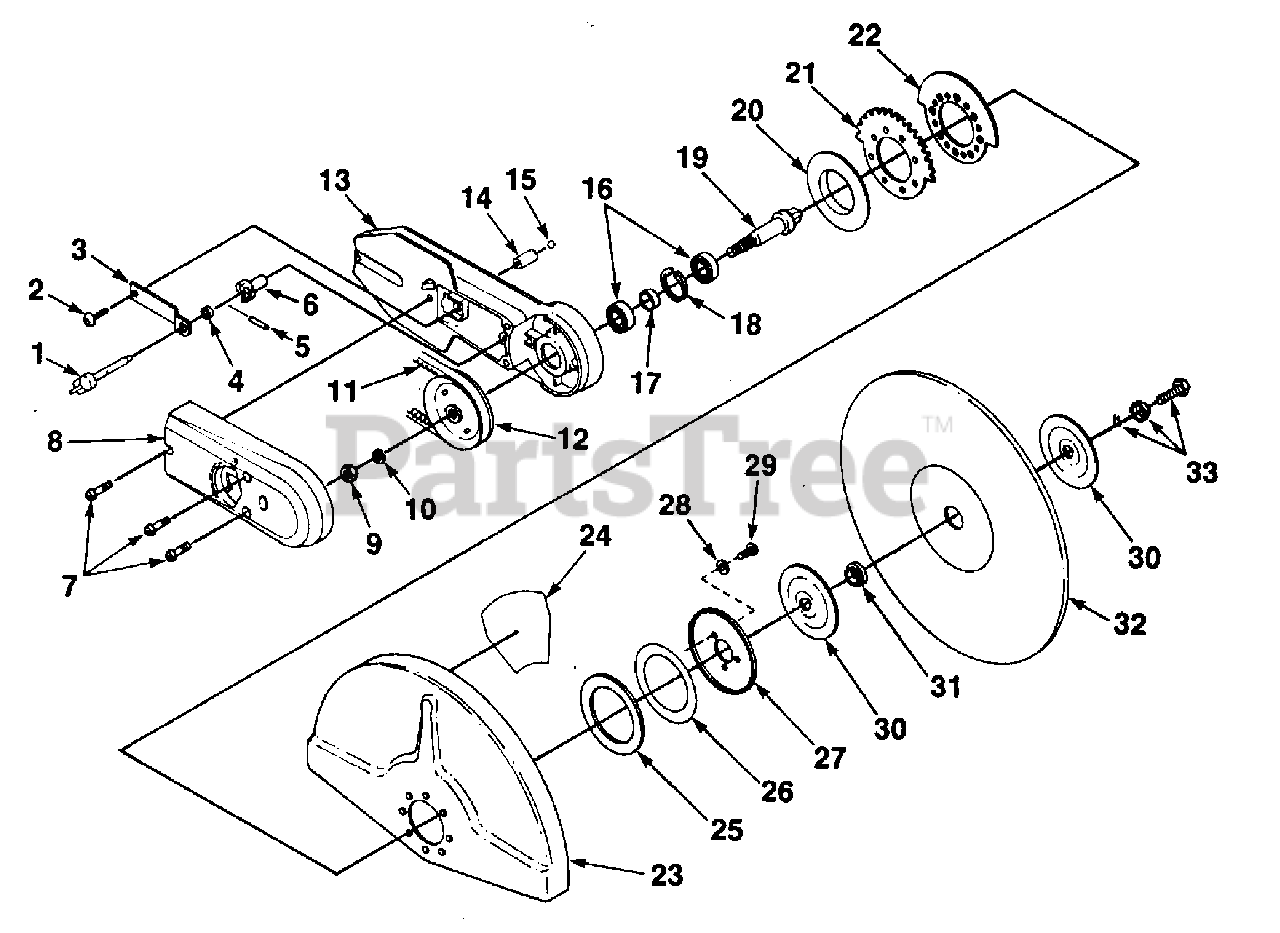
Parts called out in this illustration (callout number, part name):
1	KNOB- Wheel guard adjuster
2	SCREW- Truss hd. (10-24 x 3/4")
3	PLATE- Spring
4	SPACER- Adjusting pin
5	PIN- Roll
6	SLEEVE- Cam
7	SCREW- Rd. Hd. (10-24 x 23/32")
8	BELT- Cover
9	NUT- Hex (7/16-20)
10	WASHER- Flat
11	BELT-V-Drive
12	PULLEY & HUB
13	ARM- Wheel
14	SNUBBER
15	STEEL BALL
16	BEARING- Ball
17	SPACER- Bearing
18	RING- Retaining
19	SHAFT- Wheel
20	COLLAR- Wheel guard
21	PAD- Adjuster
22	DETENT- Adjuster
23	WHEEL GUARD & PLATE
24	DECAL- Caution
25	WASHER- Rubber
26	SHIM-.020"
27	WASHER- Spring
29	SCREW- Truss hd. (10-24 x 1/2")
30	FLANGE- Wheel
31	SPACER (1")
32	WHEEL
33	BOLT & WASHER
